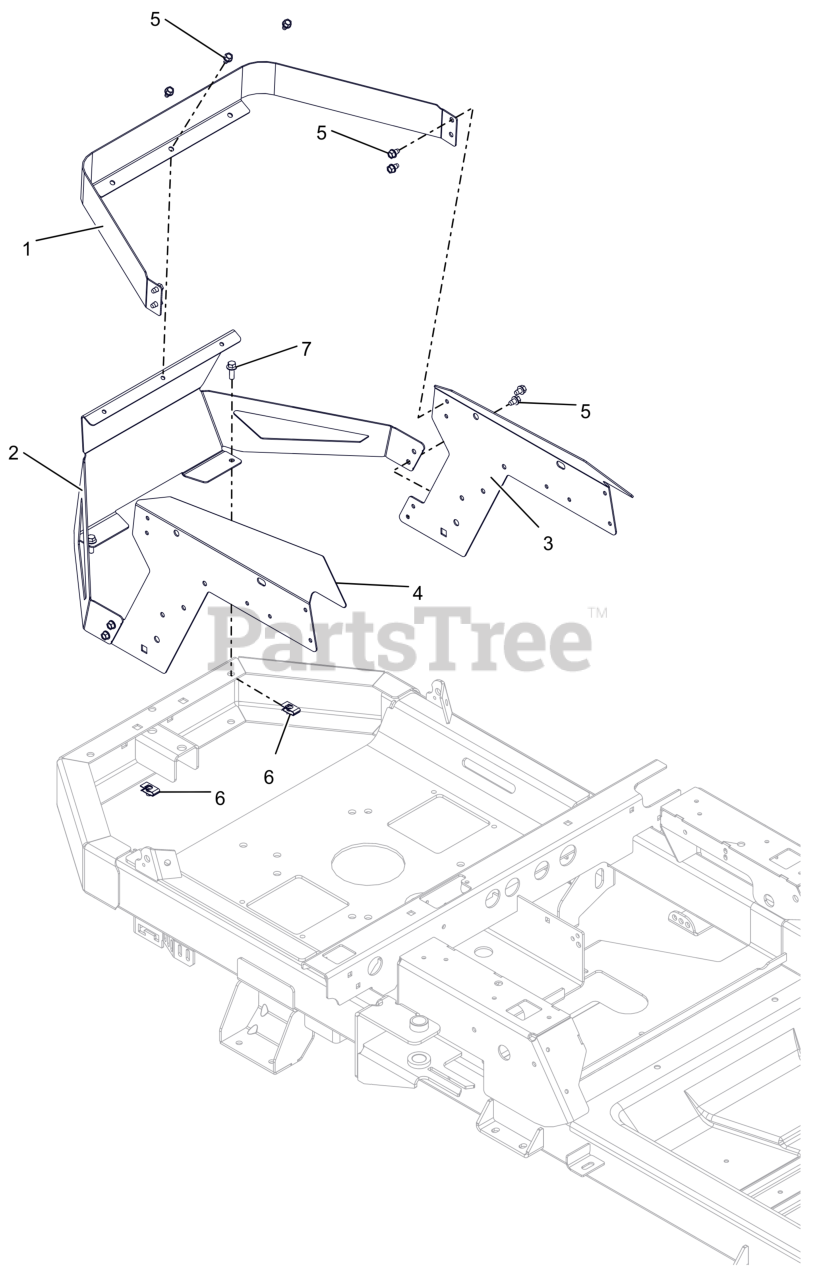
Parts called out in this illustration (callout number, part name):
1	GUARD, ENGINE -TOP TRIM
2	GUARD, ENGINE-BOTTOM BLACK
3	PANEL, LEFT REAR RENDER MOUNT
4	PANEL, RIGHT REAR FENDER MOUNT
5	SCR,TAP .25-20X.375 HWH TR ZCC
6	NUT-RTNR .25-20X.56
7	BLT,HEX-FLG .25-20X.75 G5 BFP
